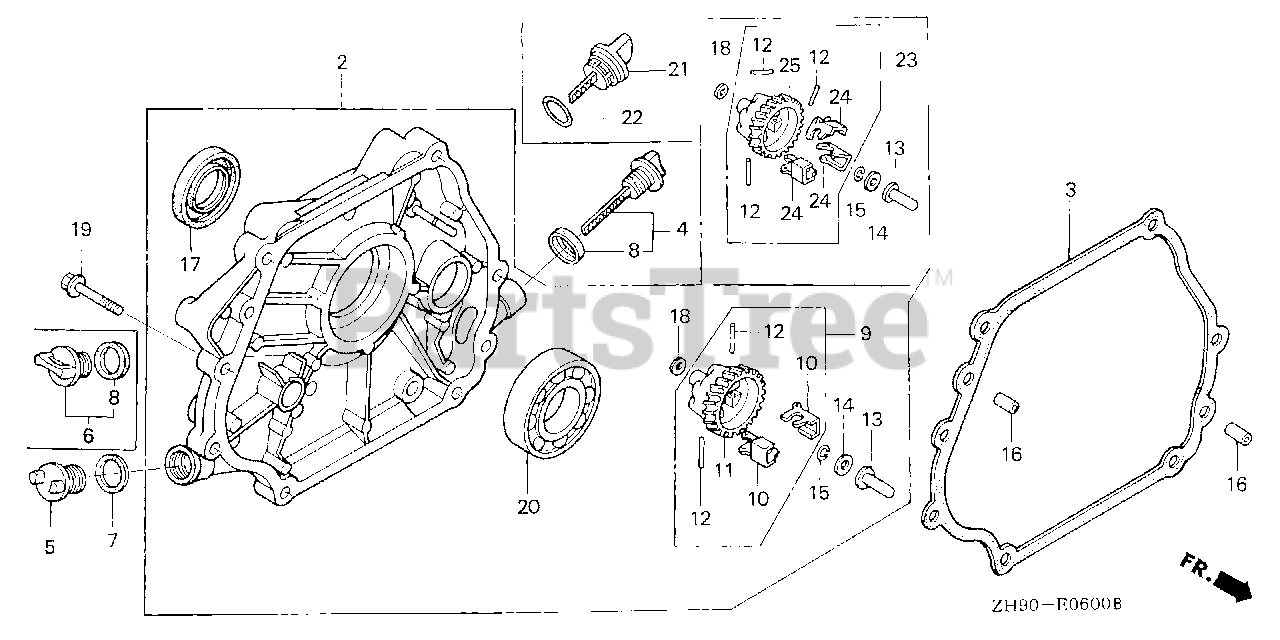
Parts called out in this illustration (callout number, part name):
2	COVER ASSY., CRANKCASE
3	GASKET, CASE COVER
4	CAP ASSY., OIL FILLER
6	CAP ASSY., OIL FILLER
8	GASKET, OIL FILLER CAP
9	GOVERNOR ASSY. (STD)
10	WEIGHT, GOVERNOR
11	HOLDER, GOVERNOR WEIGHT
12	PIN, GOVERNOR WEIGHT
13	SLIDER, GOVERNOR
15	CLIP, GOVERNOR HOLDER
16	PIN, DOWEL (8X12)
17	OIL SEAL (30X46X8)
18	WASHER, PLAIN (6MM)
19	BOLT, FLANGE (8X35)
20	BEARING, RADIAL BALL (6206)
